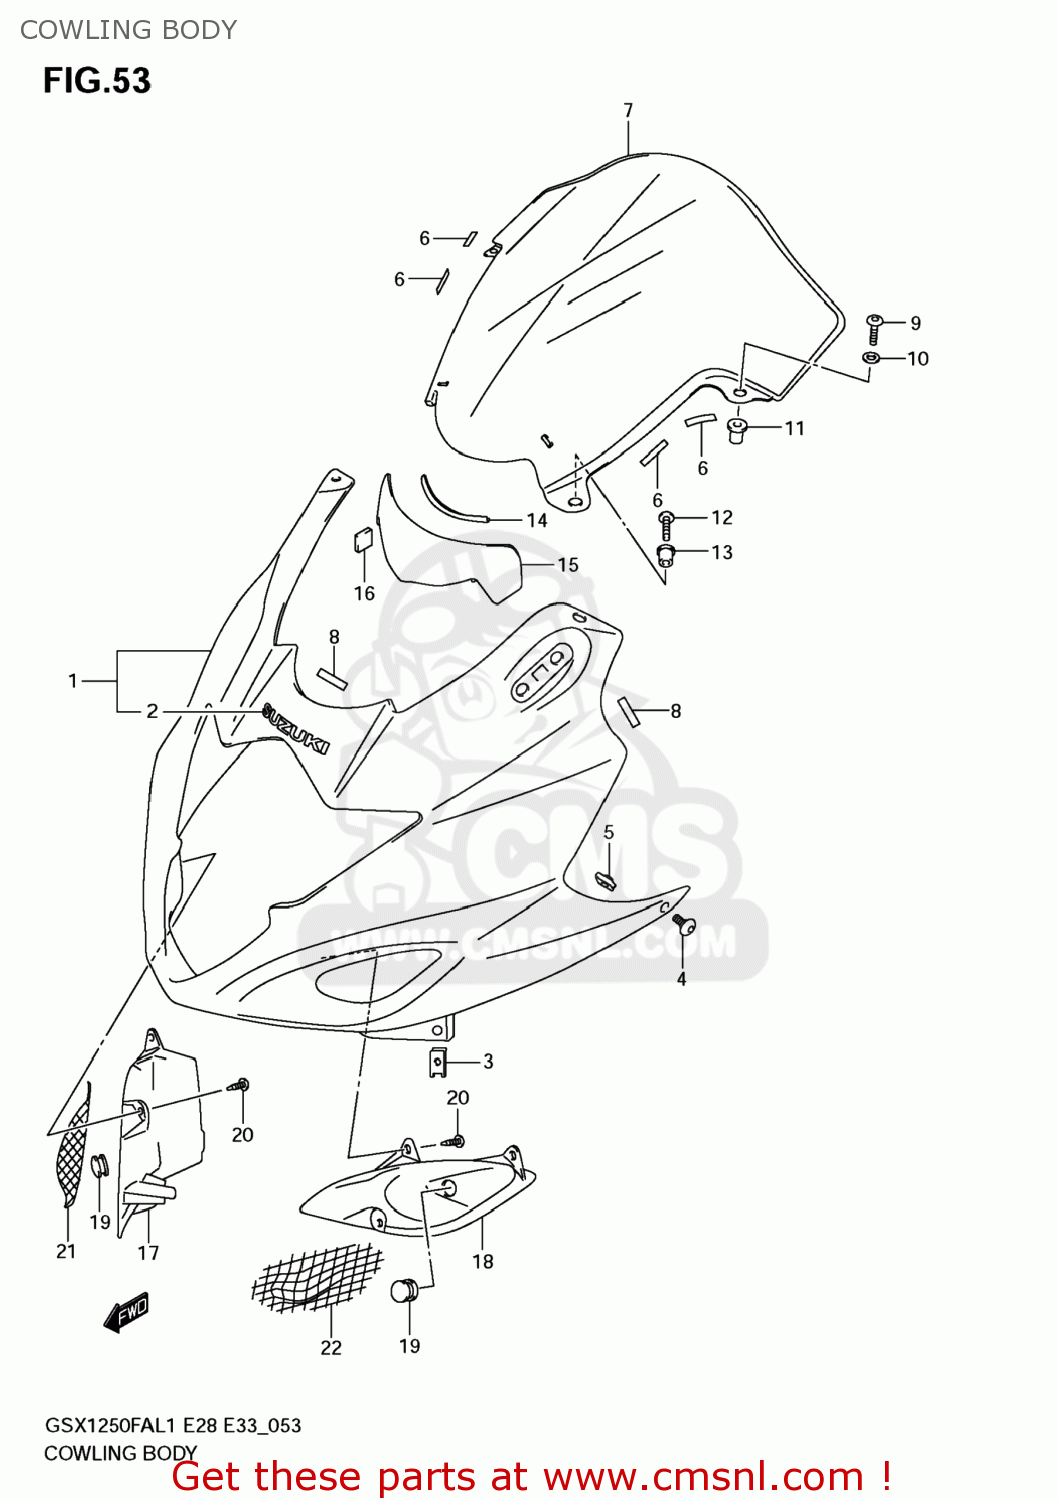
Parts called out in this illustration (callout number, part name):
1	BODY,COWLING(BLACK)
2	EMBLEM,SUZUKI
3	NUT,COWL
4	SCREW(5X16)
5	NUT
6	TAPE(6X25X0.13)
7	WINDSCREEN
8	TAPE(6X25X0.13)
9	SCREW(5X16)
10	WASHER
11	NUT
12	SCREW
13	NUT
14	CUSHION,WINDSCREEN
15	COVER,WINDSCREEN
16	PROTECTOR,20X2
17	COVER,INTAKE,R
18	COVER,INTAKE,L
19	CAP,TANK RAIL
20	SCREW
21	NET,INTAKE,R
22	NET,INTAKE,L
